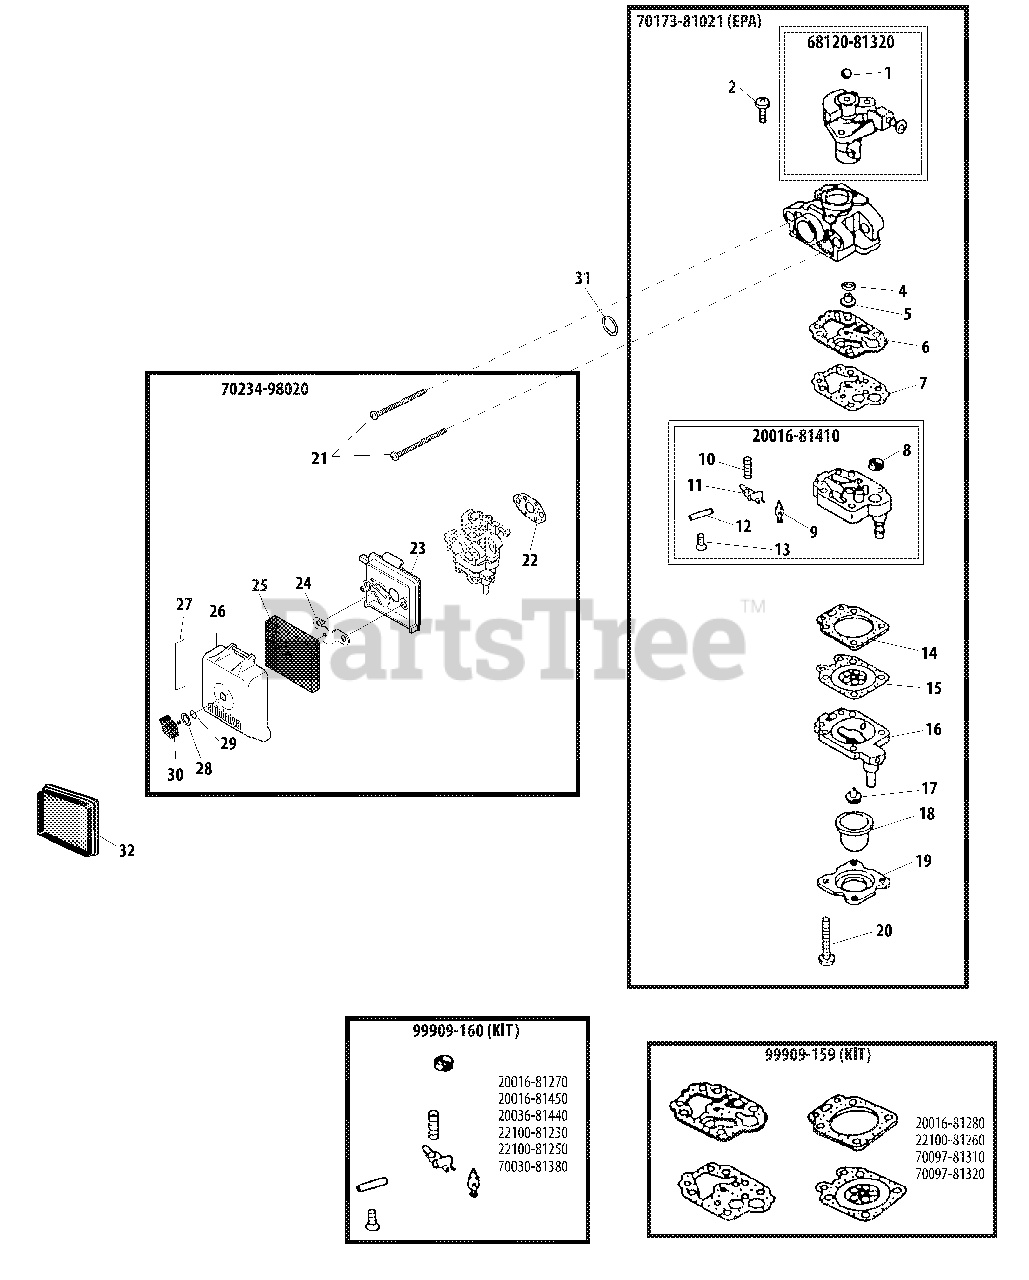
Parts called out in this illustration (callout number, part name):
1	BALL
2	SCREW, THROTTLE COLLAR
4	O-RING
5	JET, MAIN #40
6	GASKET, PUMP
7	DIAPHRAGM, PUMP
8	SCREEN, FUEL INLET
9	VALVE, INLET NEEDLE
10	SPRING, METERING LEVER
11	LEVER, METERING
12	PIN, METERING LEVER
13	SCREW
14	GASKET, METERING DIAPHRAGM
15	DIAPHRAGM, METERING
16	BODY ASSY, PURGE
17	VALVE, CHECK
18	BULB, PURGE
19	RETAINER, PURGE BULB
20	SCREW
21	SCREW - 5×67
22	GASKET, CARBURETOR
23	CASE, AIR FILTER
24	BRACKET
25	FILTER, AIR
26	COVER, AIR FILTER
27	LABEL, CHOKE
28	WASHER, CONE M6
29	O-RING
30	THUMBSCREW
31	O-RING 15
32	FILTER, AIR
20016-81410	BODY ASSY, PUMP
68120-81320	VALVE, THROTTLE
70173-81021	CARBURETOR
70234-98020	AIR FILTER ASSY
99909-159	GASKET / DIAPHRAGM KIT
99909-160	VALVE KIT, INLET NEEDLE
